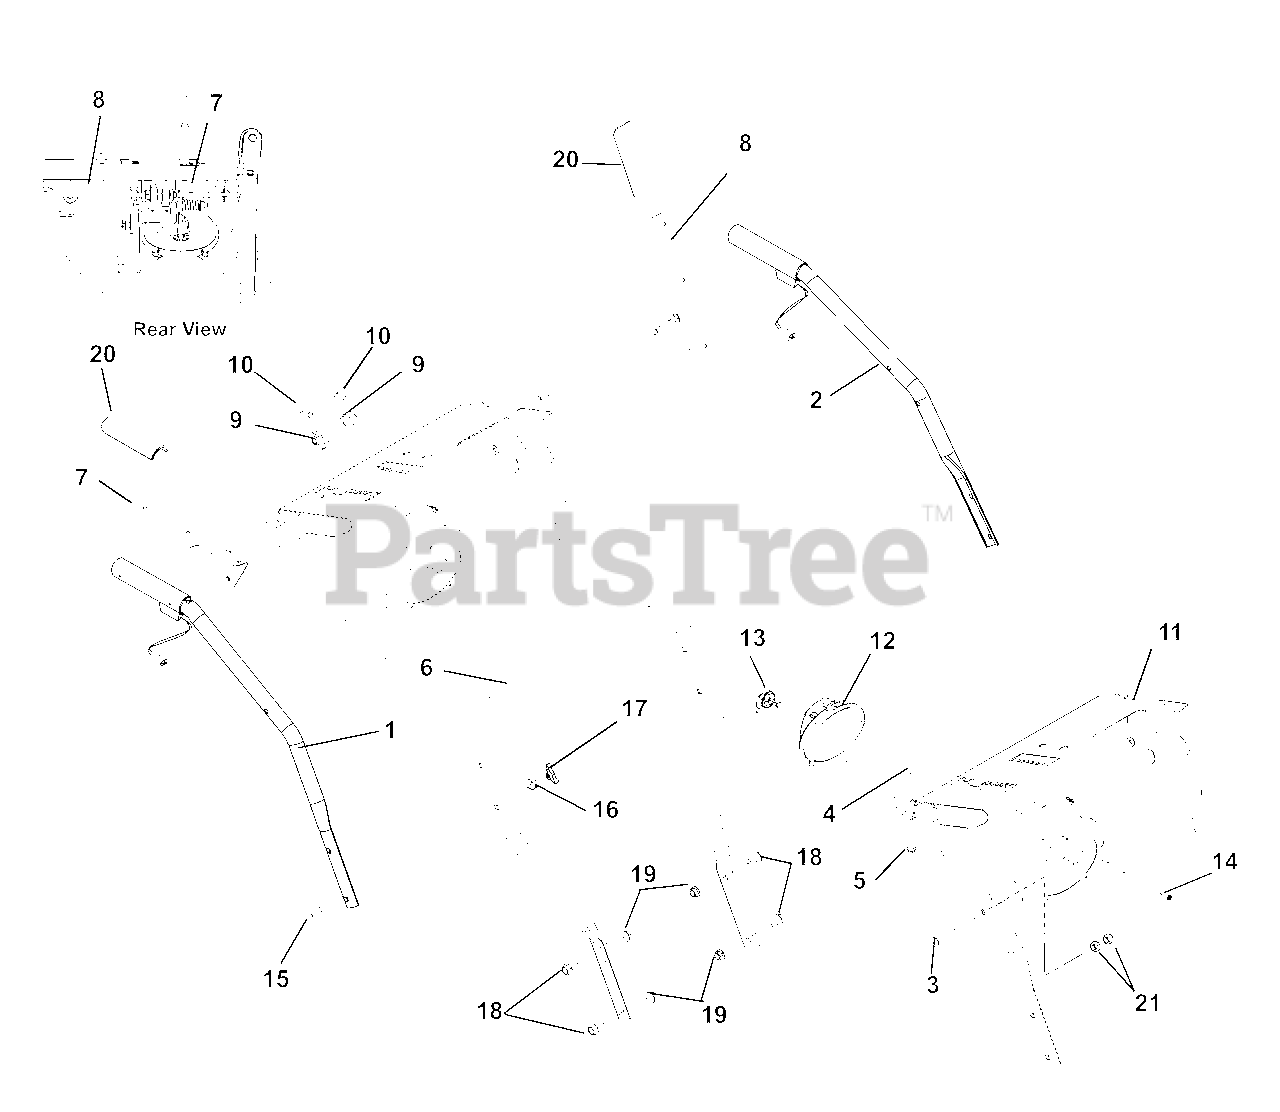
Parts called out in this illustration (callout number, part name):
1	Handlebar, Upper Right Hand with Handwarmer
2	Handlebar, Upper Left Hand with Handwarmer
3	Bolt, Round Head Square Neck .31-18 x 1.75 Grade 5
4	Bolt, Round Head Square Neck .25-20 x 1.25
5	Nut, Locking Top Flange .25-20
6	Handlebar, Lower
7	Lever, Right Hand-Attachment
8	Lever, Left Hand-Traction
9	Cam, Interlock
10	Pin, Spring Clip
11	Panel with Control Decal Gravely Brush
12	Light, Halogen Assy.
13	Bulb, Light Halogen
14	Screw, Tapping 10-16 x .75 Hi-Lo
15	Bolt, Round Head Square Neck .31-18 x 2.25
16	Spacer, Handlebar
17	Knob, Wing .31-18
18	Bolt, Screw Hex Flanged Whiz Lock Head .38-16 x .75
19	Nut, Locking-Top-Flange .38-16
20	Grip, Clutch Lever
21	Nut, Locking-Center .31-18
